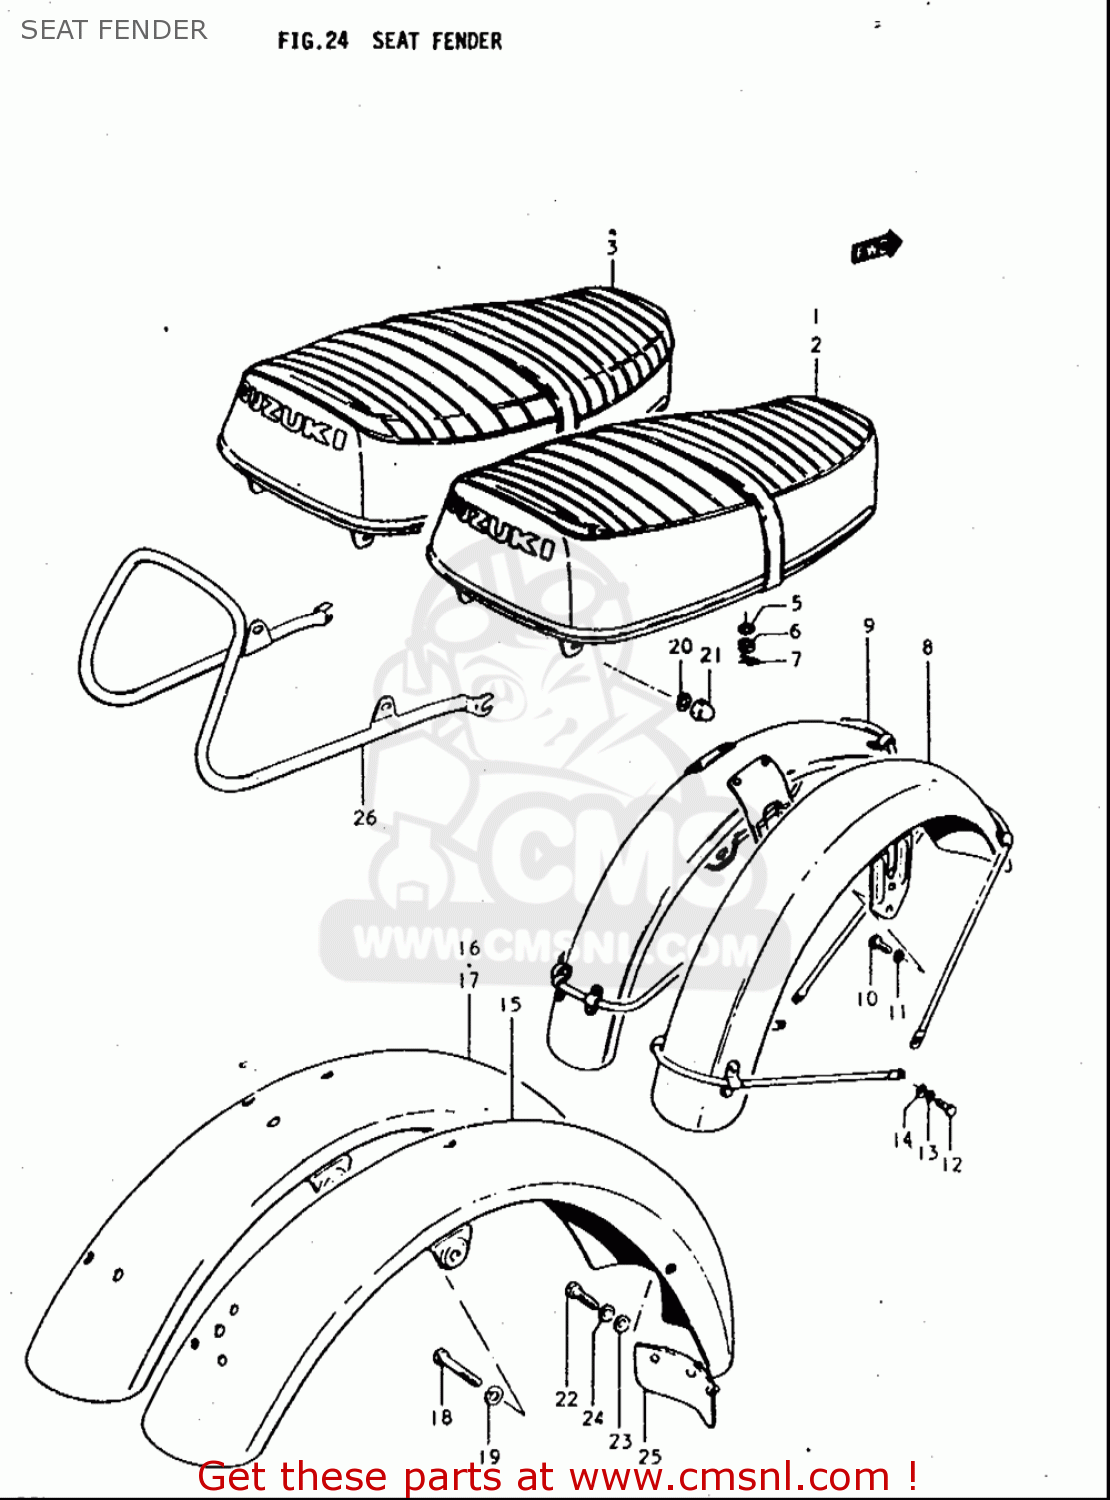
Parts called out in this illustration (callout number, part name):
5	WASHER
6	NUT
7	CLIP
10	BOLT
11	WASHER,LOCK
13	WASHER,LOCK
14	WASHER
18	BOLT(8X47)
19	WASHER
20	WASHER,LOCK
21	NUT
22	BOLT(8X14)
23	WASHER
24	WASHER,LOCK
